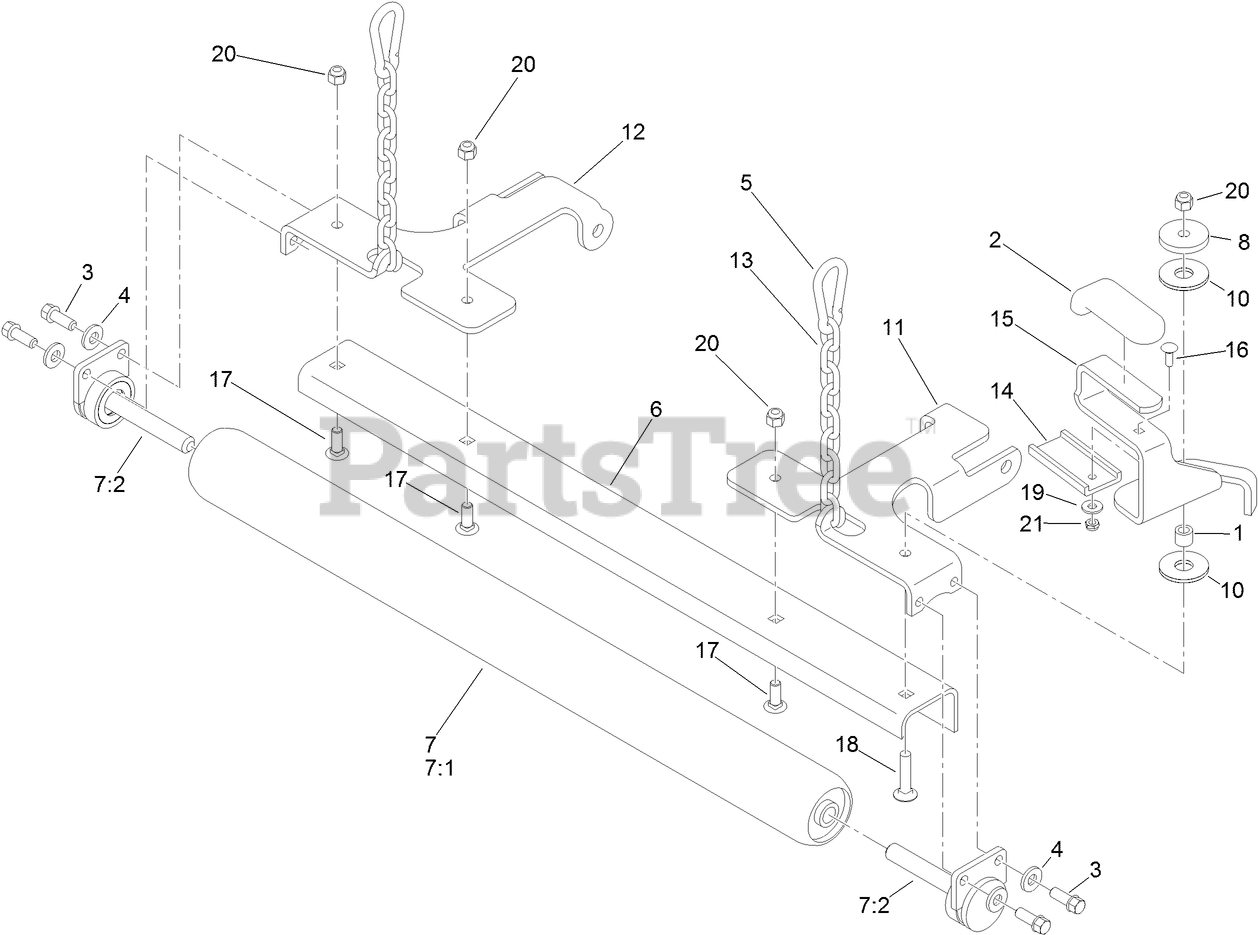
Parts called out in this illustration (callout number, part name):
1	BUSHING-LEVER, LIFT
2	GRIP-LEVER
3	SCREW-HWH
4	WASHER-BELLEVILLE
5	LINK-SNAP
6	SCRAPER-ROLLER
7	ROLLER ASM
7:1	ROLLER-STRIPER
7:2	HUB ASM
8	WASHER-PLAIN
10	WASHER-FRICTION, COMPOSITE
11	MOUNT-ROLLER, RH
12	MOUNT-ROLLER, LH
13	CHAIN-LINK, STRAIGHT
14	SLIDE-PLASTIC
15	HANDLE-ROLLER
16	BOLT-CARR
17	SCREW-CARR
18	SCREW-CARR
19	WASHER-FLAT
20	NUT-LOCK, NI
21	NUT-LOCK, NI
